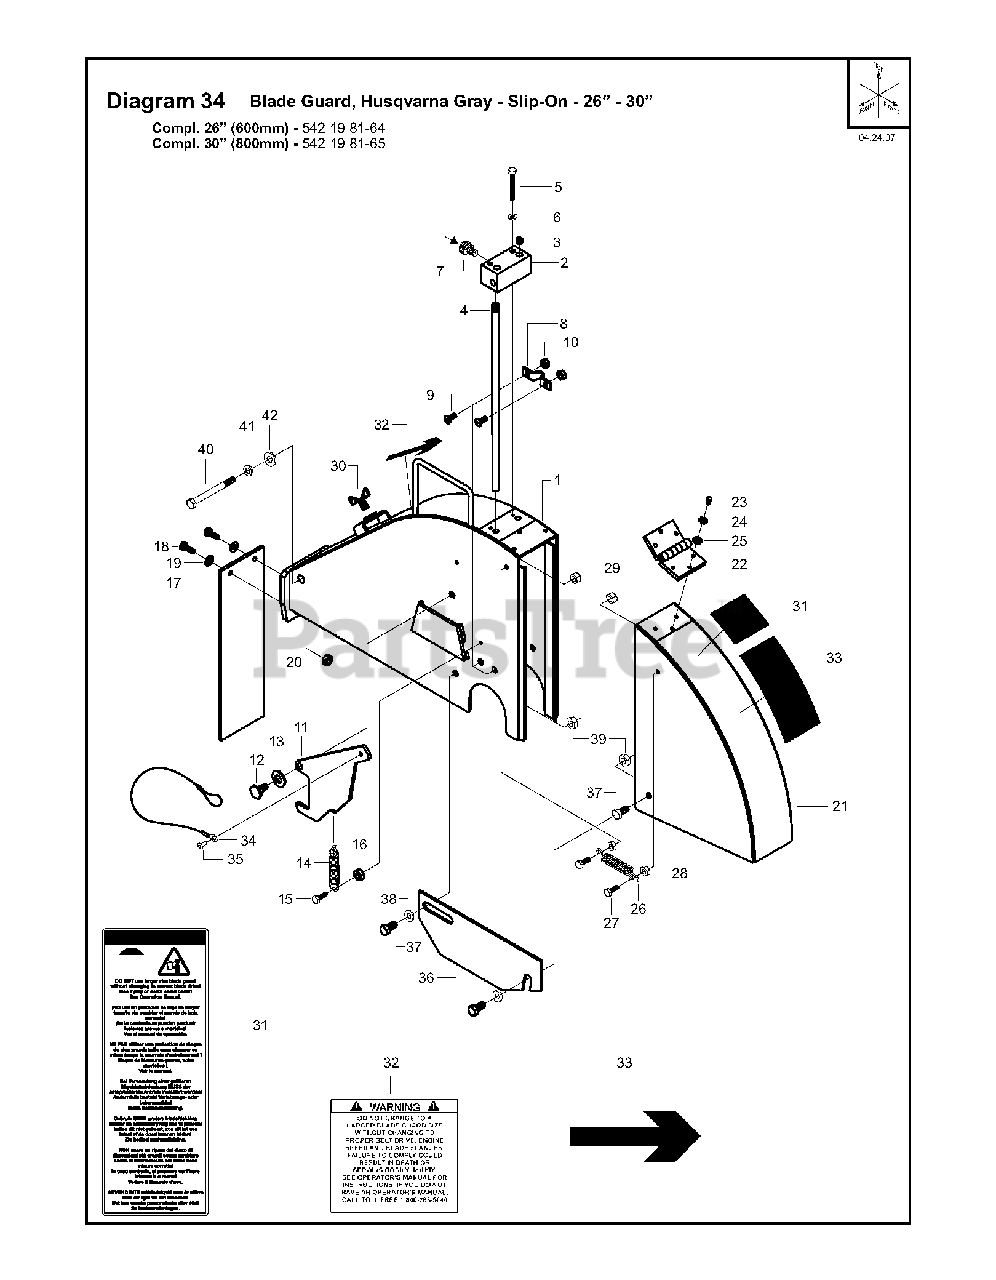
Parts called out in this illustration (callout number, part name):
1	BLD GRD WLMT.REAR 30".PC H-GRY
5	HHCS. M6 x 1.0 x 45 DIN931 Z/P
6	LOCKWASHER. SPLIT M6
7	FITTING. HOSE .375 x .75GHT
9	FLHMS. M6 x 1.0 x 16mm SLOT
10	LOCKNUT. FIBER M6 DIN 985
13	WASH.FIBER 10Dx.40625IDx.09375
15	HHCS. M5 x 0.8 x 20 DIN933 Z/P
16	NUT
17	GUARD. SPLASH 12"
18	GRIP HANDLE DLM
19	WASHER
20	LOCKNUT. FIBER M6 DIN 985
23	HHCS. M8 x 1.25 x 20 DIN933 ZP
24	LOCKWASHER. STAR EXTERNAL M-8
25	WASHER
27	GRIP HANDLE DLM
28	NUT
29	LOCKNUT. FIBER M6 DIN 985
30	WINGBOLT: M6 X 16 DIN931
34	LANYARD. NYLON COATED S. S.
37	HHCS. M12 x 1.75 x 25 DIN933ZP
39	LOCKNUT. FIBER M12 DIN 985 Z/P
40	HHCS M16 x 2.0 x 110 DIN931 ZP
